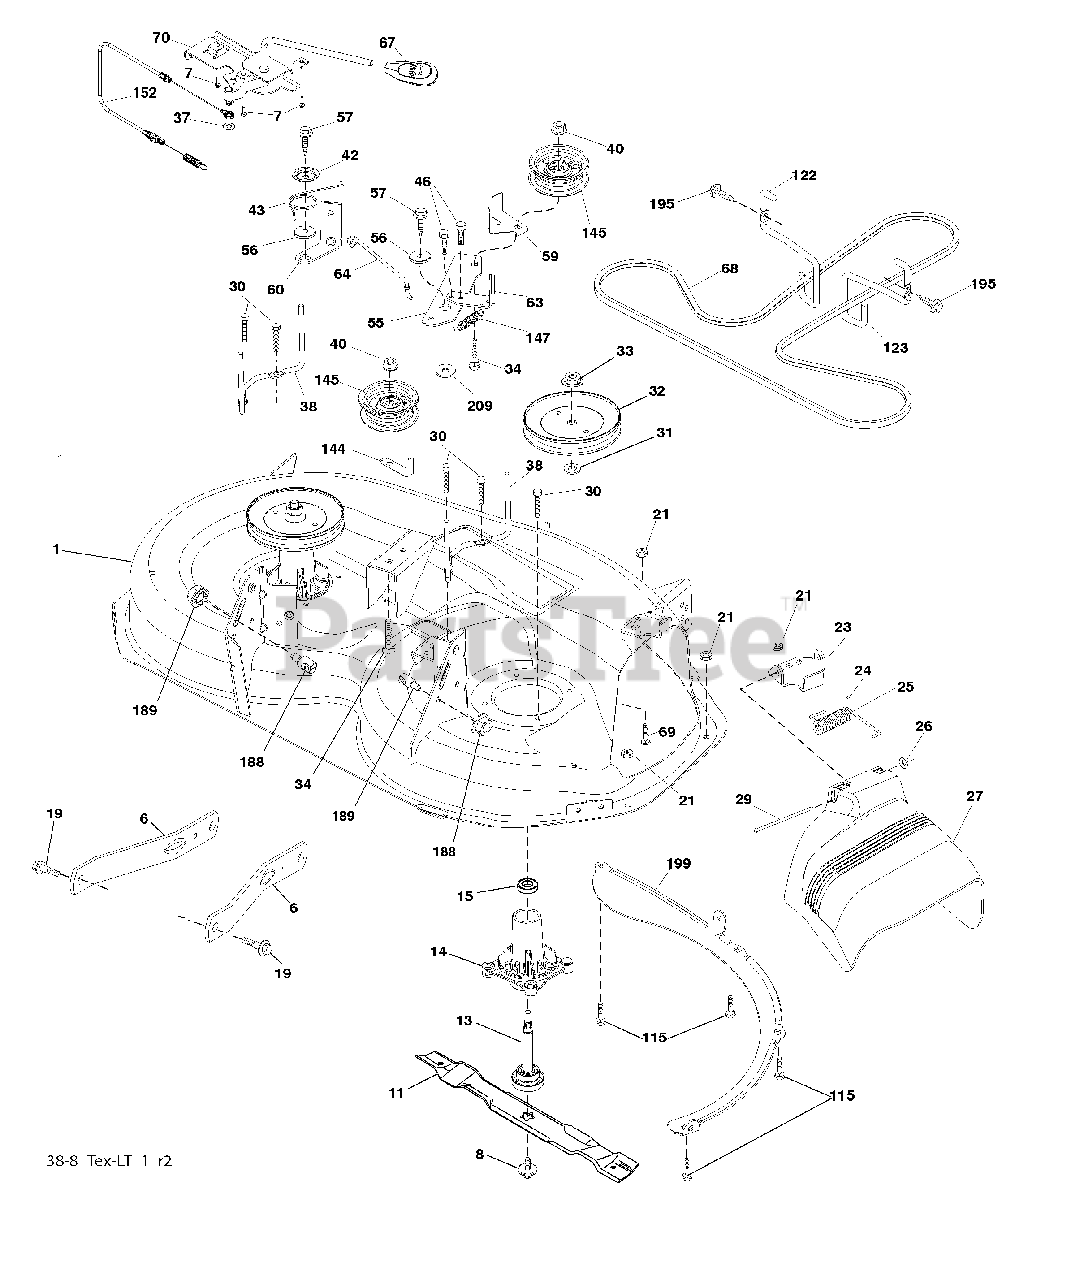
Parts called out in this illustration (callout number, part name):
1	Mower Housing
6	Arm Suspension
7	Screw #10 x 0.750 BOS Thread
8	Bolt/Washer Asm 7/16-20 unf
11	Blade
13	Shaft Assembly, Mandrel
14	Housing, Mandrel
15	Bearing, Ball, Mandrel
19	Bolt, Shoulder
21	Nut, Crownlock 5/16-18 unc
23	Bracket, Deflector
24	Cap, Sleeve
25	Spring, Torsion, Deflector
27	Shield, Deflector
29	Rod, Hinge
30	Screw Thdrol Rolling Wsh Hd
31	Washer, Spacer
32	Pulley, Mandrel
33	Nut, Toplock, Flanged
34	Bolt Carr Sh. 3/8-16 x 1-1/2 Gr. 5
37	Washer
38	Keeper Belt LH Mandrel
40	Nut, Lock Flg. 3/8-16 unc
42	Spring Torsion Brake
43	Spring Torsion Retainer
46	Screw 1/4-20 x 5/8
55	Arm, Idler
56	Spacer, Retainer
57	Screw 3/8-16 x 1
59	Guard, Tuv Idler
60	Arm Brake Mower
62	Bolt Carr. 3/8-16 x 1-1/2
63	Arm Brake Mower
64	Link Brake
67	Handle Clutch Cable
69	Bolt
70	Clutch Asm Manual
115	Bolt Carr. 5/16-18 x 5/8
116	Bolt, Shoulder
117	Wheel, Gauge
118	Nut Lock 3/8-16 unc
119	Washer 3/8 x 7/8 x 14 Ga.
122	Keeper Belt Engine LH
123	Keeper Belt Engine RH
144	Keeper Belt
145	Pulley Idler
147	Spring Return
149	Retainer Spring
152	Manual Clutch Cable
188	Stud Fastener
189	Nut Lock Hex Flange
195	Screw 3/8-16 x 3/4
199	Baffle Vortex
209	Washer 13/32 x 2 x 10
209	Mandrel Assembly
209	Replacement Mower, Complete
